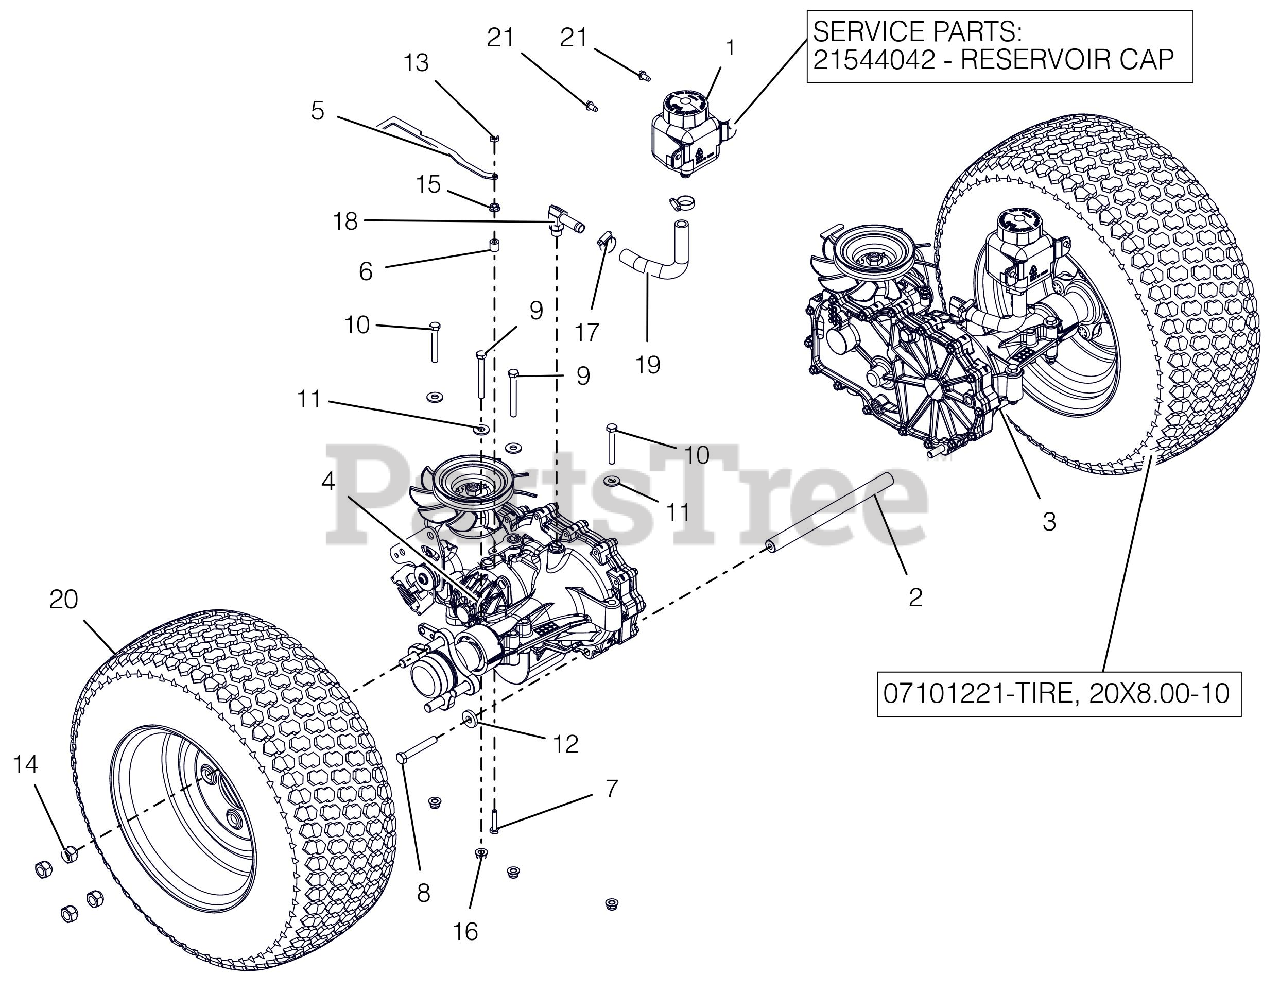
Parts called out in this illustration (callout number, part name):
1	TANK, EXPANSION
1	CAP, HYDRO RESERVOIR REPLAC.
2	ROD, TRANSAXLE BRACE (LONG)
3	TRANSAXLE,ZT2800 LH
4	TRANSAXLE,ZT2800 RH
5	BRKT, DUMP VALVE
6	BSHG-SLV .265X.500X.500
7	@BLT-HEX .25-20X1.25 GR5 YWZC
8	@BLT-HEX .38-16X2.50 GR5 YWZC
9	@BLT-HEX .31-18X2.75 GR5 YWZC
10	@BLT-HEX .31-18X2.25 GR5 YWZC
11	@WSHR-FL-STL.38X.875X.083 YWZC
12	WSHR-FL-STL .406X1.00X.188 YWZ
13	NUT-LK-CTR JAM .25-20 YWZC
14	WHEEL NUT .500-20 YZ
15	@NUT-SPNLK-FLG .25-20 YWZC
16	@NUT-LK-NYL-FLG .31-18 YWZC
17	CLAMP,.88 DIA. HOSE
18	FITTING, HYD (90 DEG)
19	HOSE, FORMED LH XL
20	ASM, WHL/TIRE 20X8.00-10
20	TIRE, 20X8.00-10
20	TUBE, 20X10-10
21	SCR-TAP .25-20X.50 HWH TR YWZ
